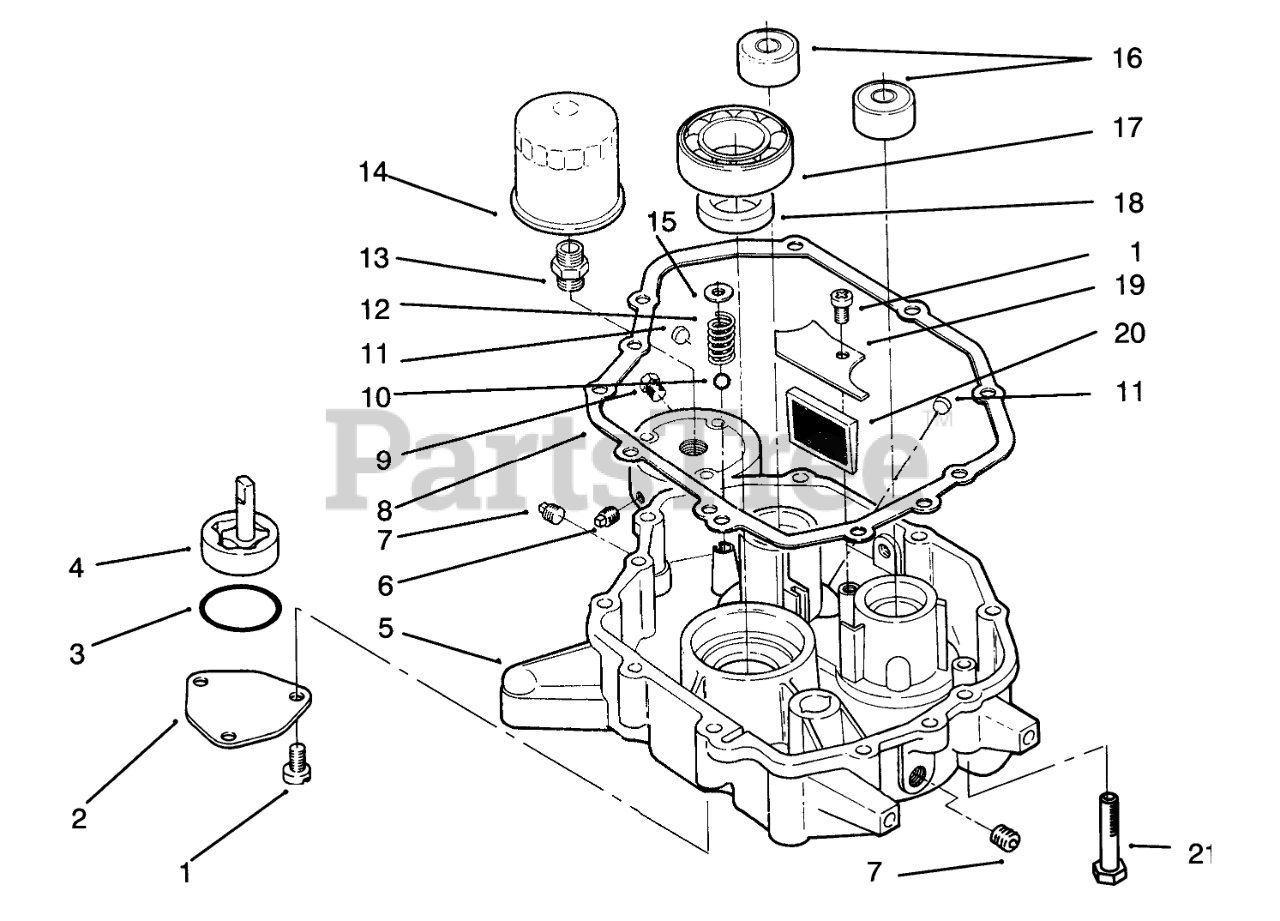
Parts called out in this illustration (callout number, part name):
1	SCREW-M6 X 14
2	COVER-OIL PUMP
3	RING-O
4	PUMP-OIL
5	BASE-0IL
6	PLUG-COUNTERSUNK HD
7	PLUG - SQUARE HEAD
8	Gasket
9	PLUG-HEX HD
10	BALL-BEARING
11	Plug
12	Spring
13	ADAPTER
14	FILTER
15	RETAINING-RING
16	BRNG-BALL BAL SHFT L
17	BRNG-BALL CRANKSH L
18	SEAL-OIL CRNKSHFT UP
19	COVER
20	SCREEN
21	SELF-TAP BOLT SP M8
